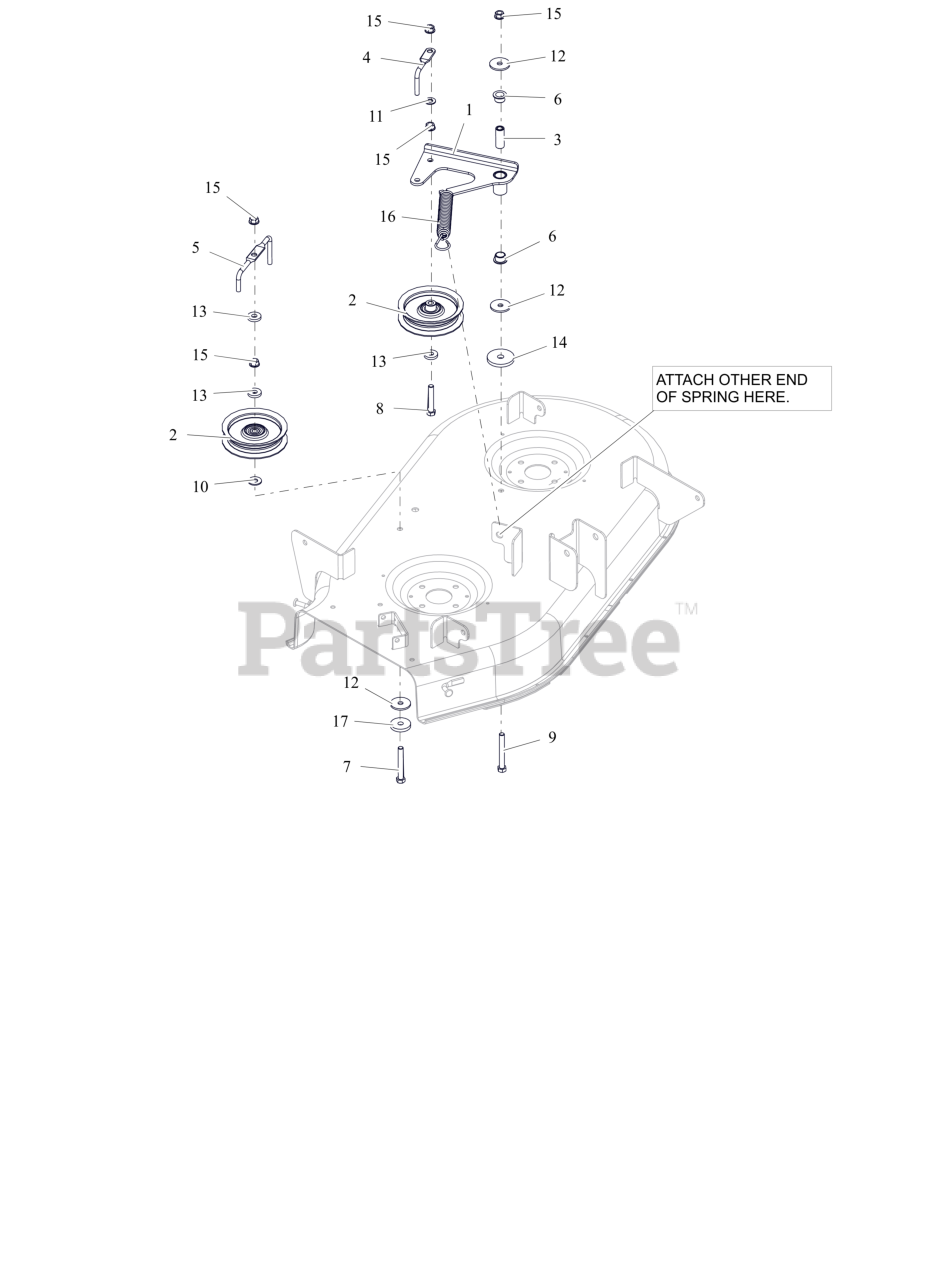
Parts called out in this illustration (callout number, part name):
1	WLDMT, IDLER ARM (ORANGE)
2	IDLER, FLAT - 4.06" X .75"
3	SPACER, .375IDX.625ODX1.66 PM
4	WIREFORM-BELT FINGER
5	BELT FINGER
6	BSHG-FLG, .625X.750X.500X1.00
7	BLT, HEX .38-16X2.75 G5 ZCC
8	BLT,HEX .38-16X2.25 G5 ZCC
9	BLT, HEX .38-16X3.00 G5 ZCC
10	WSHR,FLT .438X1.00X.083 ZCC
11	WSHR,FLT .406X.812X.065 ZCC
12	WSHR, FLT .380X1.50X.125 ZCC
13	WSHR, FLT .406X1.00X.188 ZCC
14	WSHR, FLT .469X2.00X.250 ZCC
15	NUT-LK-CTR-FLG .375-16 GF ZCC
16	SG-TENS .135X.98X6.0 WLD 62
17	WSHR, FLT .406X1.50X.245 ZCC
